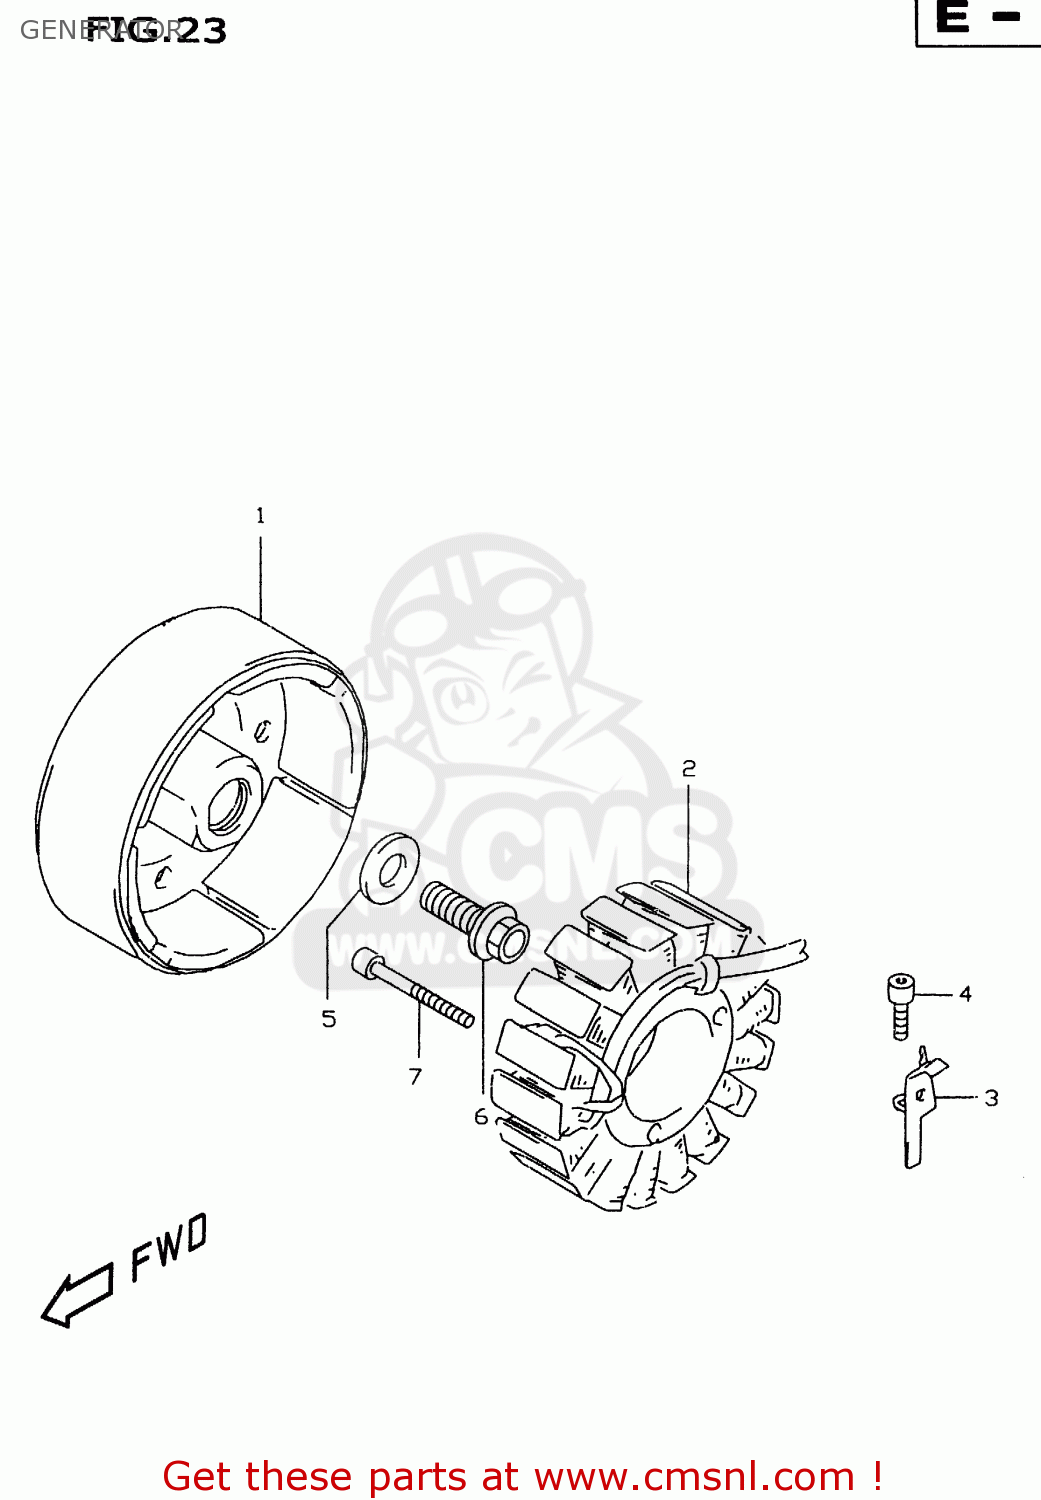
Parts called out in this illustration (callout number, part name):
1	ROTOR ASSY
2	STARTER ASSY
3	CLAMP,MAGNETO LEAD
4	BOLT(12X30)
5	WASHER(12X30X3)
6	BOLT,VAC.PIPE
7	BOLT
